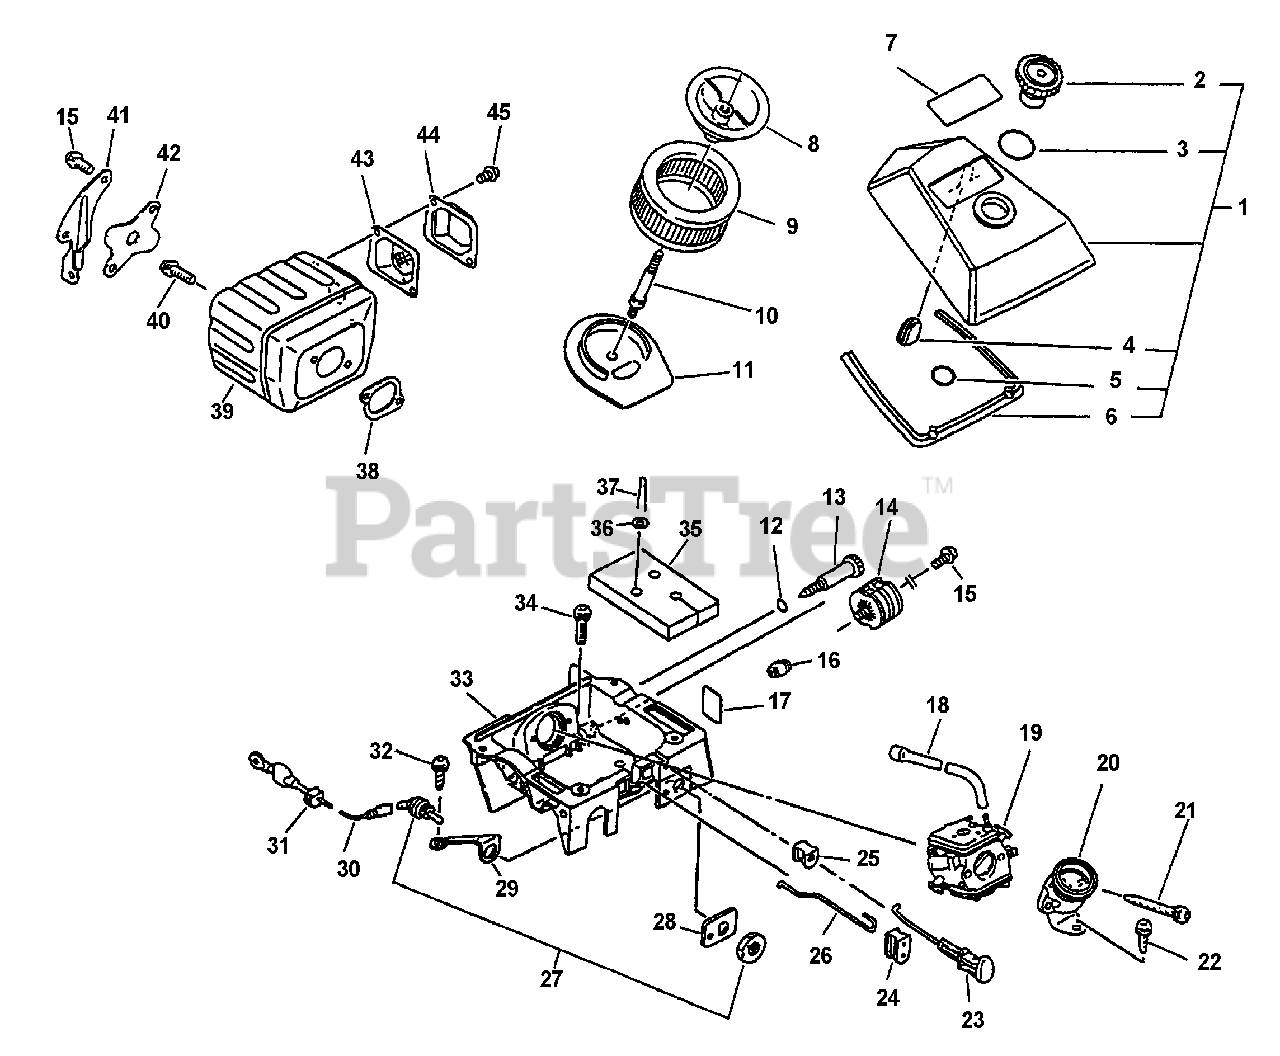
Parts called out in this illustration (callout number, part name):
1	COVER ASSY, AIR FILTER
2	THUMBSCREW
3	O-RING -21
5	O-RING P-11
6	GASKET, AIR FILTER
7	LABEL, MODEL
8	BRACKET, AIR FILTER
9	FILTER ASSY, AIR
10	STUD
11	BRACKET, AIR FILTER
12	O-RING 7
13	SCREW, IDLE ADJUST - GRAY
15	BOLT 5×14
17	LABEL, CAUTION - IDLE
18	PIPE, IMPULSE
19	CARBURETOR - HDA-151A
20	ADAPTOR, INTAKE
21	SCREW 5×53
22	SCREW 5×14
23	ROD, CHOKE
24	GROMMET, THROTTLE ROD
25	GROMMET
26	ROD, THROTTLE
27	SWITCH, ON-OFF
28	LABEL, STOP
29	PLATE, GROUND
30	LEAD
32	SCREW 4×10
33	CASE, CARBURETOR
34	BOLT 5×20
35	GASKET, CARBURETOR CASE
37	PIN, COTTER 3×18
38	GASKET, EXHAUST
39	MUFFLER
40	BOLT 5×20
41	BRACKET, MUFFLER
42	COVER, MUFFLER
43	SCREEN, SPARK ARRESTER
44	OUTLET, EXHAUST
45	BOLT 4×10
